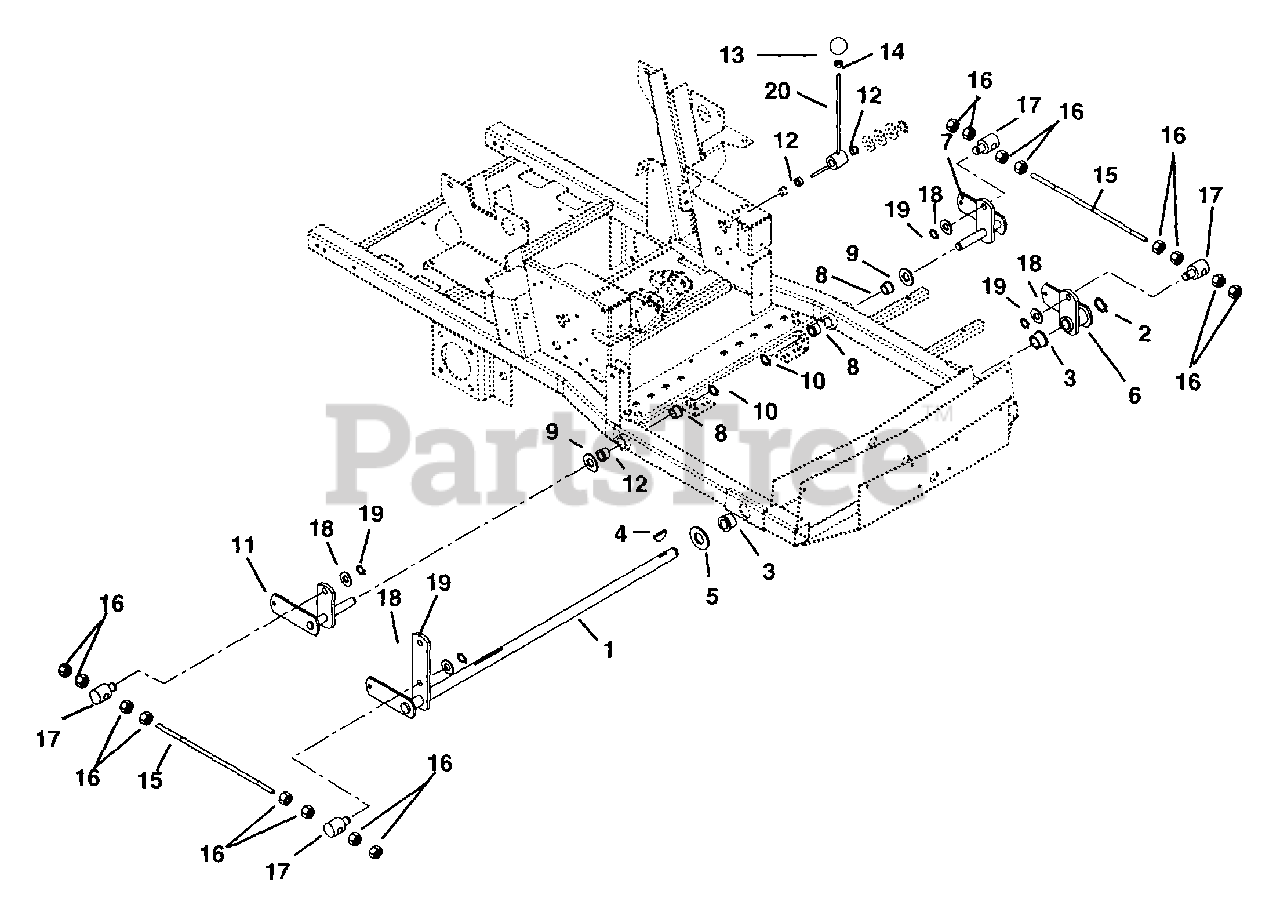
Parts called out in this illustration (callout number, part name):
1	Lift-Mower
2	Ring-Retaining-External 1.00 x .078
3	Bushing-Flange-Nylon 1.020 x 1.385 x .75 x 1.75
4	Key-Woodruff .25 x 1.00
5	Washer-Flat-Steel 1.063 x 2.00 x .134
6	Weldment, Lift Arm-Front
7	Weldment, Lift Arm-Shaft-Left Hand
8	Bushing-Flange-Nylon .762 x 1.0 x .580 x 1.48
9	Washer-Hardened-Steel .758 x 1.23 x .031
10	Ring-Retaining-External .689 x .077
11	Weldment, Lift Arm Shaft-Right Hand
12	Bushing-Flange .630 x 1.000 x .625
13	Knob-Steering Lock
14	Nut-Hex-Jam .375 -16
15	Rod-Lift Assist
16	Nut-Jam .50-13
17	Pivot-Mower Lift
18	Washer-Flat-Steel .630 x 1.005 x .062
19	Ring-Retaining-External .625 x 050
20	Lever-Deck Lift
